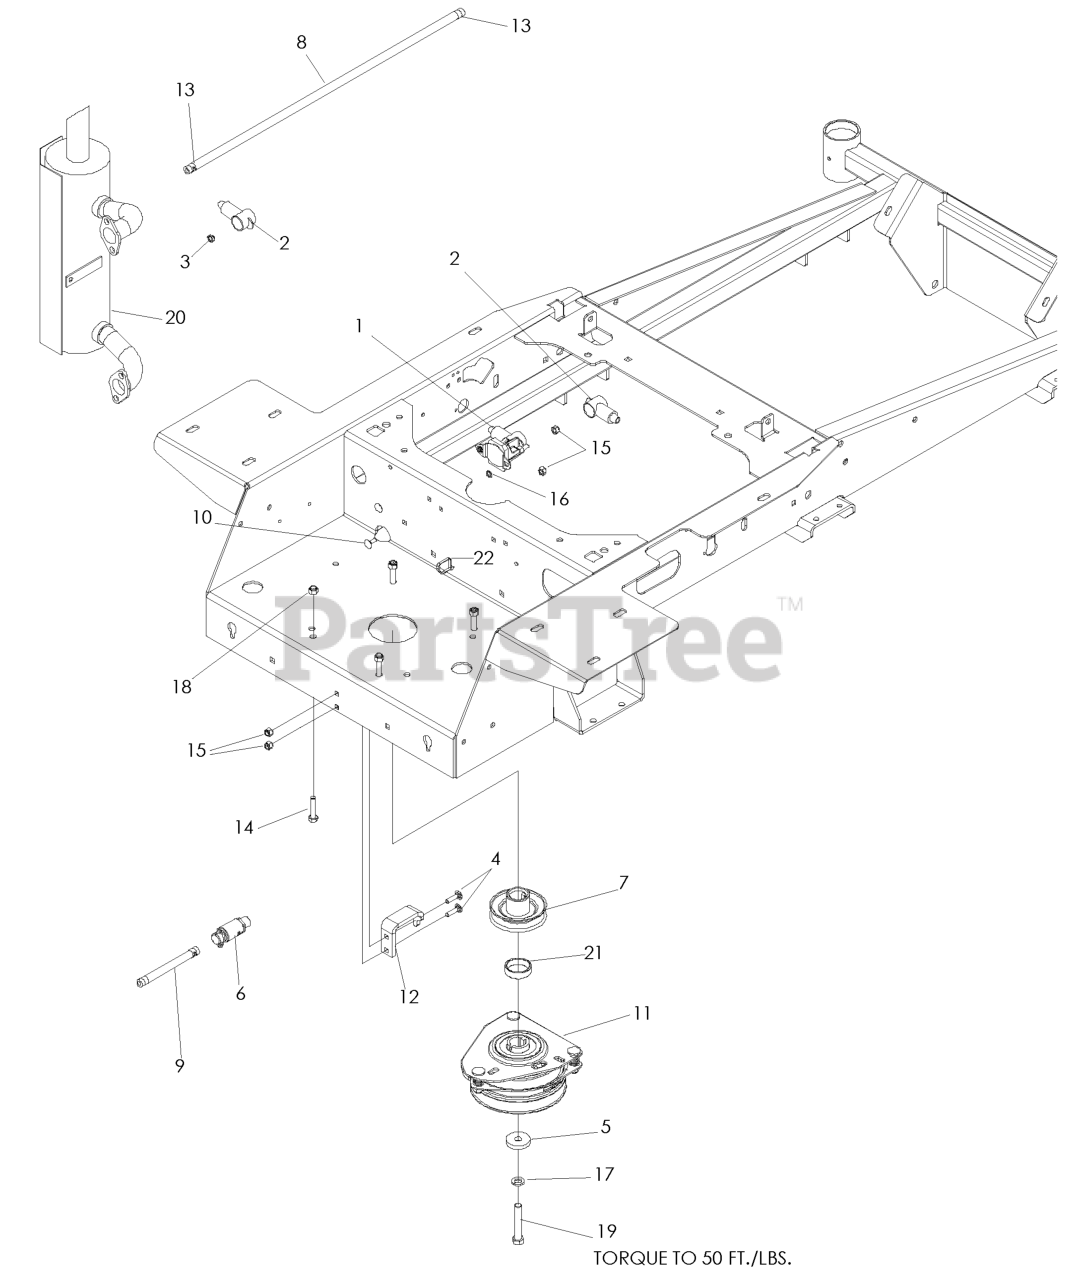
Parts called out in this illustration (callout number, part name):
3	JAM NUT 1/4C (2 2 PW01)
4	RHSNB, 1/4-20 X 1, GR5
5	CLUTCH, WASHER
6	OIL DRAIN FITTING
7	PULLEY, ENGINE
8	FUEL LINE 24"
9	FUEL LINE 5"
10	RHSSNB, 1/4-20X5/8
11	CLUTCH.ELECTRIC.LT.48"*
12	CLUTCH TIE DOWN
13	HOSE CLAMP
14	CAPSCREW 5/16 X 1/1/2 HEX HEAD
15	NUT.1/4-20.HEX.NYLOC.ZD
16	WASHER 1/4 INT TOOTH
17	WASHER 7/16 LOCK
18	NUT 5/16 NYLOC
19	BOLT 7/16F X 2 1/2
21	SPACER, ENGINE, PULLEY
22	TIE, PLASTIC
